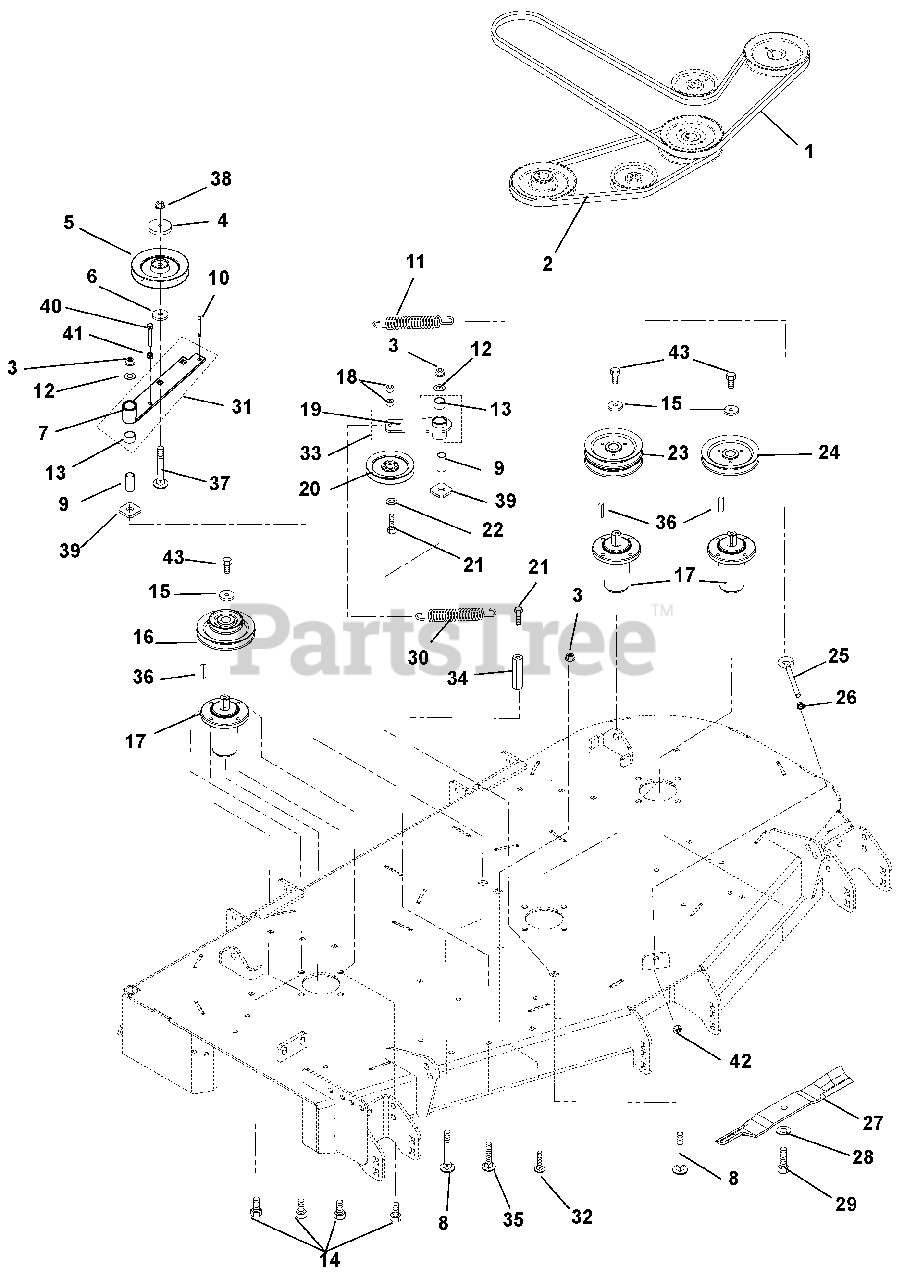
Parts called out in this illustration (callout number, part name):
1	Belt, 130" Long, PTO Drive Hex
2	V-Belt, 63" Long Cog B-Section
3	Nut, .50-13 Nyloc Flange
4	Cap, Idler Bearing Sealing
5	Sheave, .50" ID x 6.00" OD V-Idler
6	Bushing, Spacer .502 x .997 x .50
7	Weldment, Idler Arm
8	Bolt, Round Head Square Neck .50-13 x 3.50
9	Bushing, Spacer .502 x .997 x 2.03
10	Bolt, Shoulder .38-16 x .30 Hex
11	Spring, Extension
12	Washer, Flat Steel .563 x 1.38 x .109
13	Bushing, 1.00 x 1.125 x 1.936
14	Bolt, Hex .38-16 x 1.00
15	Retainer, Sheave
16	Sheave, Double, 1" ID x 6.75" x 4.25" OD
17	Spindle Assembly
18	Nut, Locking Center .38-16
19	Weldment, Idler Arm
20	Assembly, V-Idler 5.00 O.D.
21	Bolt, Hex .38-16 x 2.25
22	Washer, Flat Steel .406 x .812 x .065
23	Sheave, Double 1" ID x 6.75" OD
24	Sheave, Single 1" ID x 6.75" OD
25	Bolt, .38-16 x 5.50 .62 Diameter Eye
26	Nut, Hex, Jam .375-16
27	Blade, Mower (20.50")
28	Washer, Bellville .63 x 1.625 x.14
29	Bolt, Hex .62-18 x 1.75 Grade 8
30	Spring, Extension
31	Assembly, PTO Idler Pivot Arm (Includes item # 7 and item # 13)
32	Bolt, Round Head Square Neck .50-13 x 1.5, Full Thread, Grade 5
33	Assembly, Idler Pivot Arm (Includes item # 13 and item # 19 )
34	Nut, Coupling .375-16 x 1.75
35	Bolt, Round Head Square Neck .38-16 x 1.00
36	Key, Square .25 x .25 x 1.00
37	Bolt, Round Head Square Neck .50-13 x 3.00 Grade 5
38	Nut, Locking Center .50-13
39	Washer, Flat .640 x 1.75 x .250
40	Bolt, Hex .38-16 x 2.75
41	Nut, Hex .38-16
42	Nut, Locking Center Jam .375-16
43	Bolt, 3/8-16 x 2.75 Grade 8
